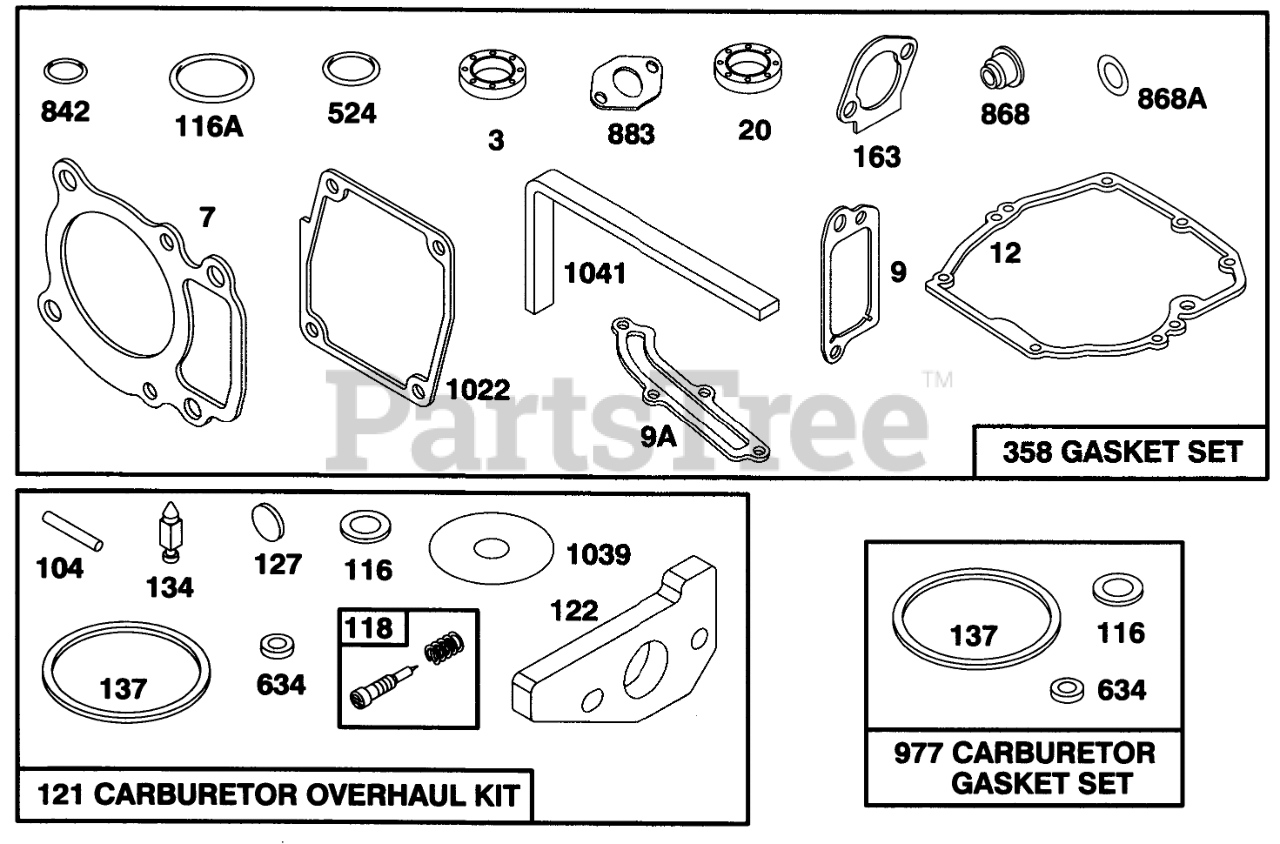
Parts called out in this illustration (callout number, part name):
3	SEAL - OIL
7	CYLINDER HEAD GASKET
9	BREATHER GASKET
9A	GASKET-BREATHER
12	ENGINE BASE GASKET
20	SEAL-OIL
104	FLOAT HINGE PIN
116	SEALING GASKET
116A	O RING SEAL
118	VALVE KIT - NEEDLE
121	CARBURATOR OVERHAUL KIT
122	ADAPTER ASSEMBLY
127	PLUG
134	Valve-Inlet(Includes Seat)
137	FLOAT BOWL GASKET
163	AIR CLEANER GASKET
358	GASKET SET
524	O-RING
634	SEAL WASHER
842	O-RING
868	SealAssy-Valve
868A	Seal-Valve
883	EXHAUST GASKET
977	CARBURATOR GASKET SET
1022	ROCKER COVER GASKET
1039	FLOAT LIMITER
1041	SEAL - FOAM
